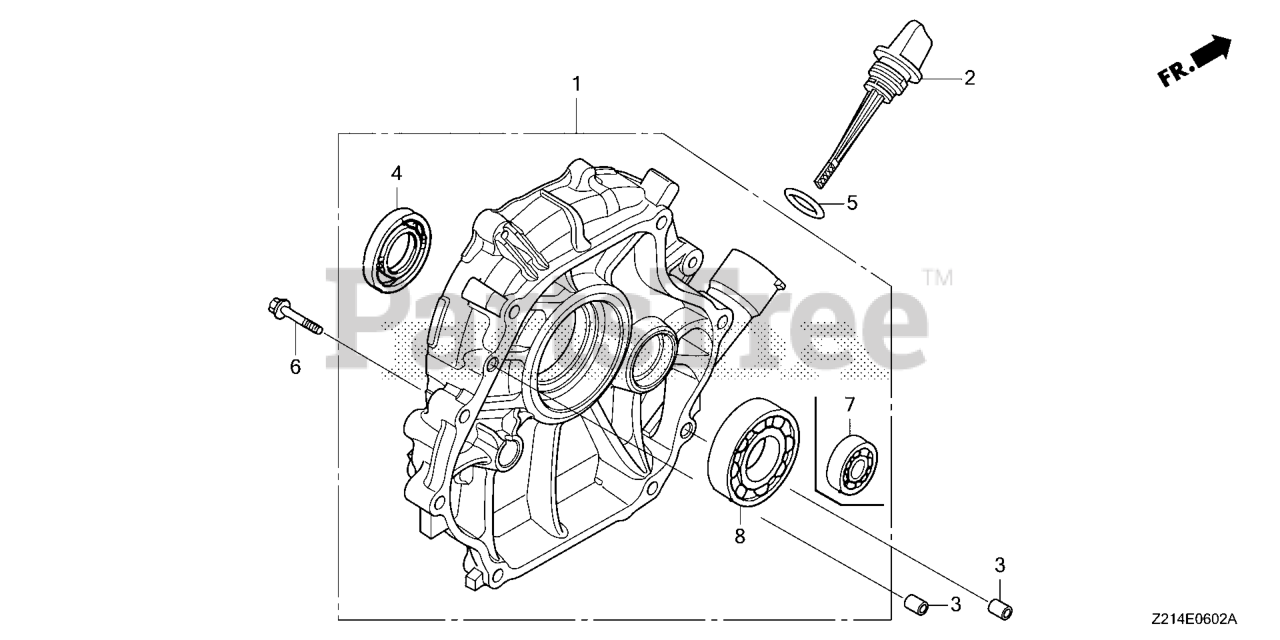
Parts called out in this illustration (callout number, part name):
1	COVER ASSY., CRANKCASE (E-TYPE)
2	CAP, OIL FILLER
3	PIN, DOWEL (8X12)
4	OIL SEAL (35X52X8) (NOK)
5	O-RING (26X2.7)
6	BOLT, FLANGE (8X40) Use up to Engine SN 1003236.
7	BEARING, RADIAL BALL (6202)
8	BEARING, RADIAL BALL (6207)
